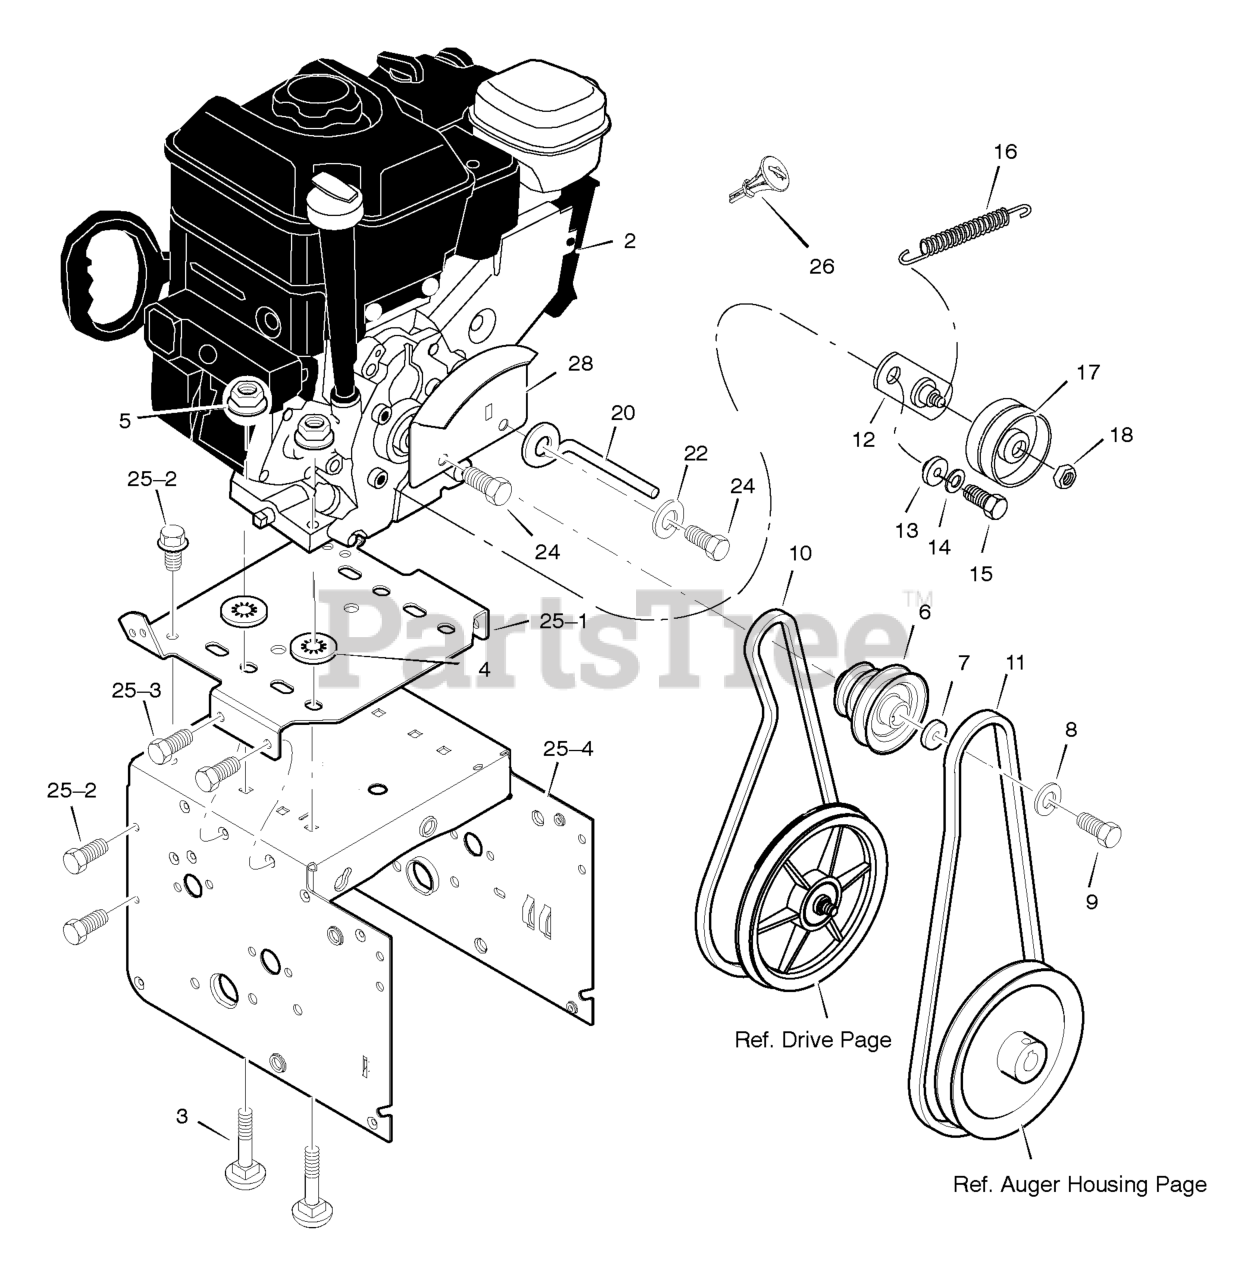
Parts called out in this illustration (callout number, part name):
2	ENGINE
3	BOLT, CARRIAGE 5/16-18
4	RETAINER, PUSH
5	NUT 5/16-18
6	PULLEY, ENGINE
7	WASHER
8	WASHER .38ID
9	SCREW, 3/8-24 x 1.00
10	BELT, V 3L
11	BELT, V 4L
12	BRACKET ASSEMBLY, IDLER
13	BUSHING, IDLER BRACKET
14	WASHER, SPLIT
15	SCREW 5/16-24 X 0.75
16	SPRING, IDLER TRACTION DRIVE
17	PULLEY, IDLER
18	NUT, JAM 3/8-16
20	GUIDE, BELT
22	WASHER .31X.58X.08
24	SCREW, 5/16-24 x 0.75
25-1	PLATE, ENGINE MOUNT
25-2	SCREW, TAP 1/4-20 X .63
25-3	SCREW, TAP 5/16-18 X .50
25-4	FRAME, MOTOR BOX
26	KEY, BRIGGS ENGINE
28	SHIELD, BRIGGS ENGINE
